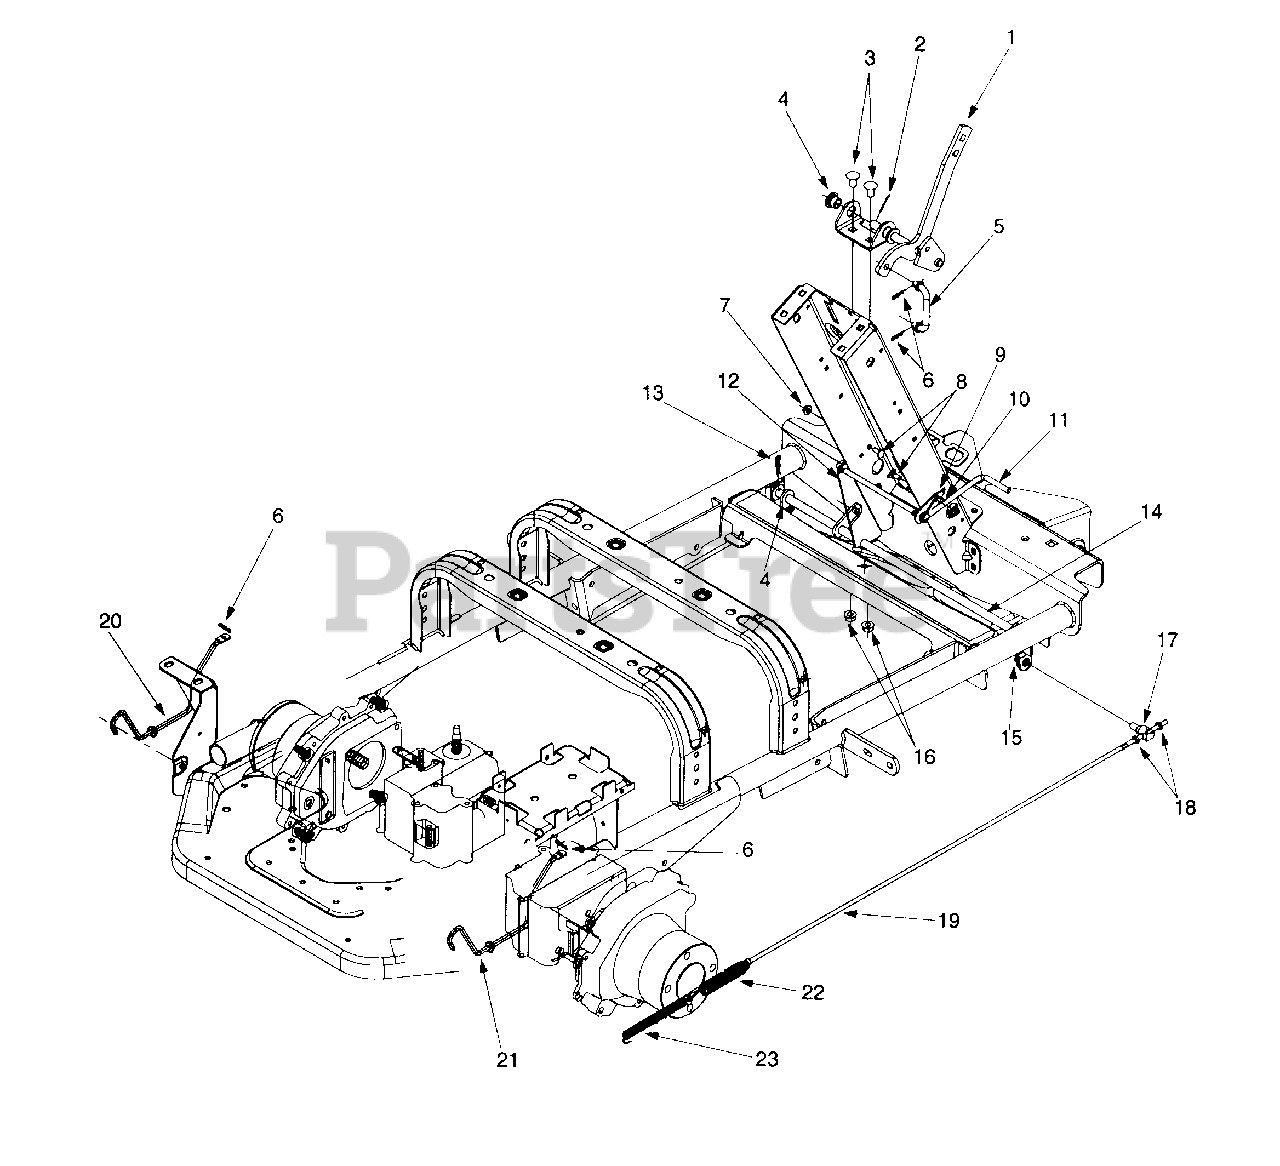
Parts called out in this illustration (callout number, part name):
1	Parking Brake Shift Ass'y
2	Cotter Pin
3	Carriage Bolt 3/8-16 x .75
4	Hex Flange Bearing .506 ID x .590
5	Connecting Brake Rod
6	Cotter Pin
7	Hex Flange Lock Nut 1/4-20
8	Carriage Screw 1/4-20 x .62
9	Retaining Rod Bracket
10	Torsion Spring 5/16
11	Parking Brake Retaining Rod
12	Support Plate
13	Cotter Pin
14	Brake Rod Ass'y
15	Flat Washer .385 ID x 1.0 OD
16	Flange Lock Nut 3/8-16
18	Jam Nut 1/4-28
19	Bracket Rod
20	Release Pump Rod LH
21	Release Pump Rod RH
22	Extension Spring
23	Extension Spring
